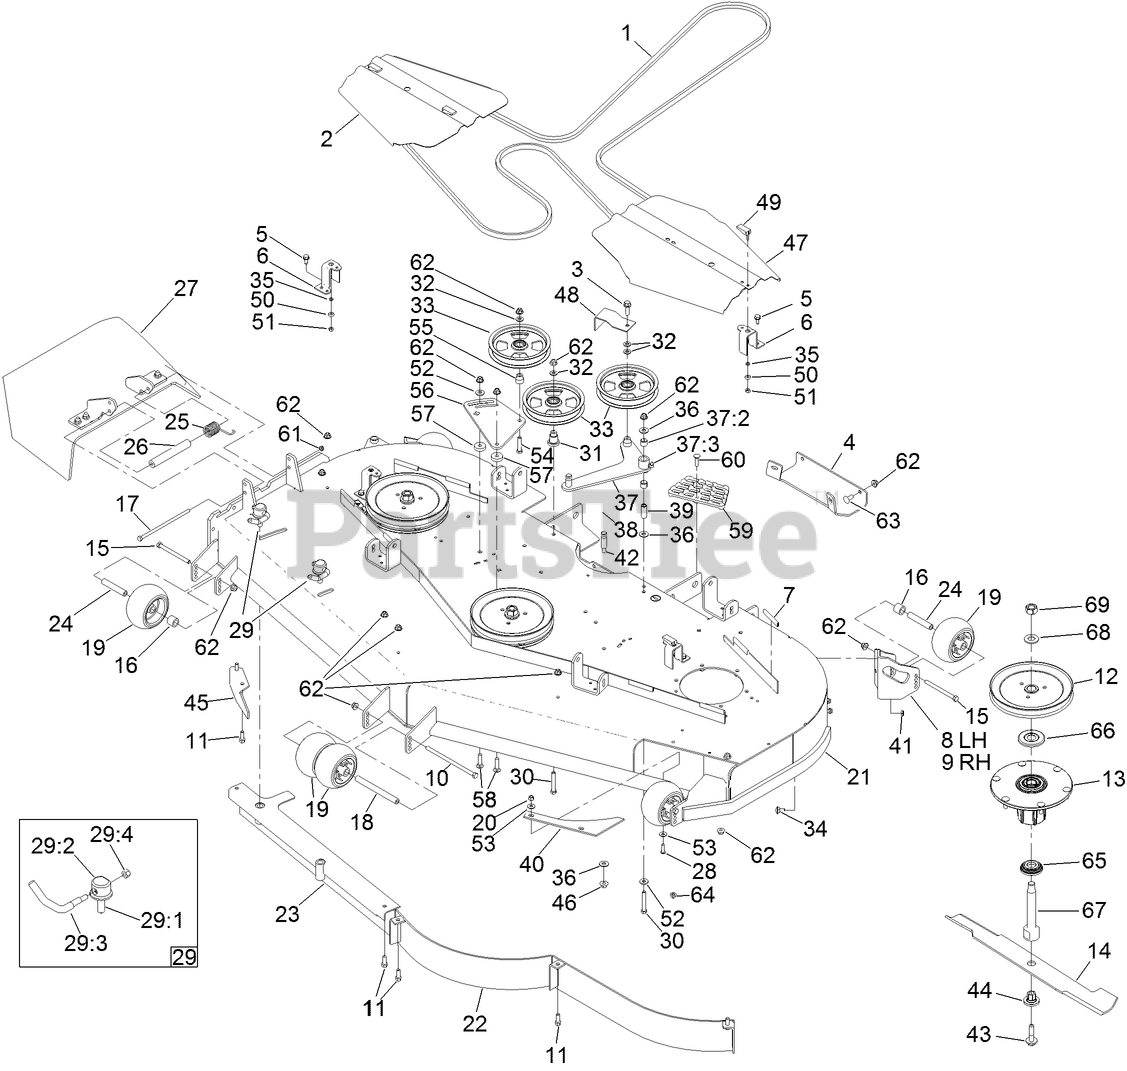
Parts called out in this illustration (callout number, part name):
2	COVER-BELT, RH
3	SCREW-HHF
4	PLATE-SKID
5	SCREW-HWHTF
6	BRACKET-COVER
7	STRIP-SEAL
8	MOUNT-WHEEL, LH
9	MOUNT-WHEEL, RH
10	SCREW-HH
12	SHEAVE-DRIVE, BLADE
13	SPINDLE ASM
15	SCREW-HH
16	TUBE-SPACER
17	SCREW-HH
18	SPACER-WHEEL
19	ROLLER-SCALP, ANTI
20	NUT-LOCK, NI
21	DECK ASM
23	BAFFLE ASM
24	TUBE-SPANNER
25	SPRING-TORSION
26	SPACER
27	RUBBER DEFLECTOR ASM
28	SCREW-HSBH
29	LEVER ASM
29:1	SCREW-LOCK
29:2	CAP-LOCK
29:4	NUT-LOCK, NI
30	SCREW-HH
31	MOUNT-PULLEY
32	WASHER-FLAT
33	PULLEY-IDLER, FLAT
34	SCREW-CARR
35	WASHER
36	WASHER-FLAT
37	DECK IDLER ARM ASM
37:2	SLEEVE-BEARING
37:3	FITTING-GREASE, 90 DEG
38	SPRING-EXTENSION
39	BUSHING
40	PLATE-TURBO
42	PIN-THREADED, SPRING ANCHOR
43	SCREW-SEMS
44	BUSHING-HEX
45	BAFFLE-DISCHARGE
46	NUT-HF
47	COVER-BELT, LH
48	GUIDE-BELT
49	HANDLE-LATCH, SWELL
50	BUSHING-LATCH, SWELL
51	NUT-LOCK, HH
52	WASHER-BELLEVILLE
53	WASHER-SPRING
54	SCREW-HH
55	BUSHING-IDLER
56	PLATE-IDLER
57	SPACER
58	SCREW-CARR
59	STEP-DECK
60	SCREW-CARR
61	NUT-LOCK, NI
62	NUT-HF, NI
63	SCREW-CARR
64	NUT-HF, NI
65	GUARD-BOTTOM
66	GUARD-BEARING, TOP
67	SHAFT-SPINDLE
68	WASHER
69	NUT-HEX
